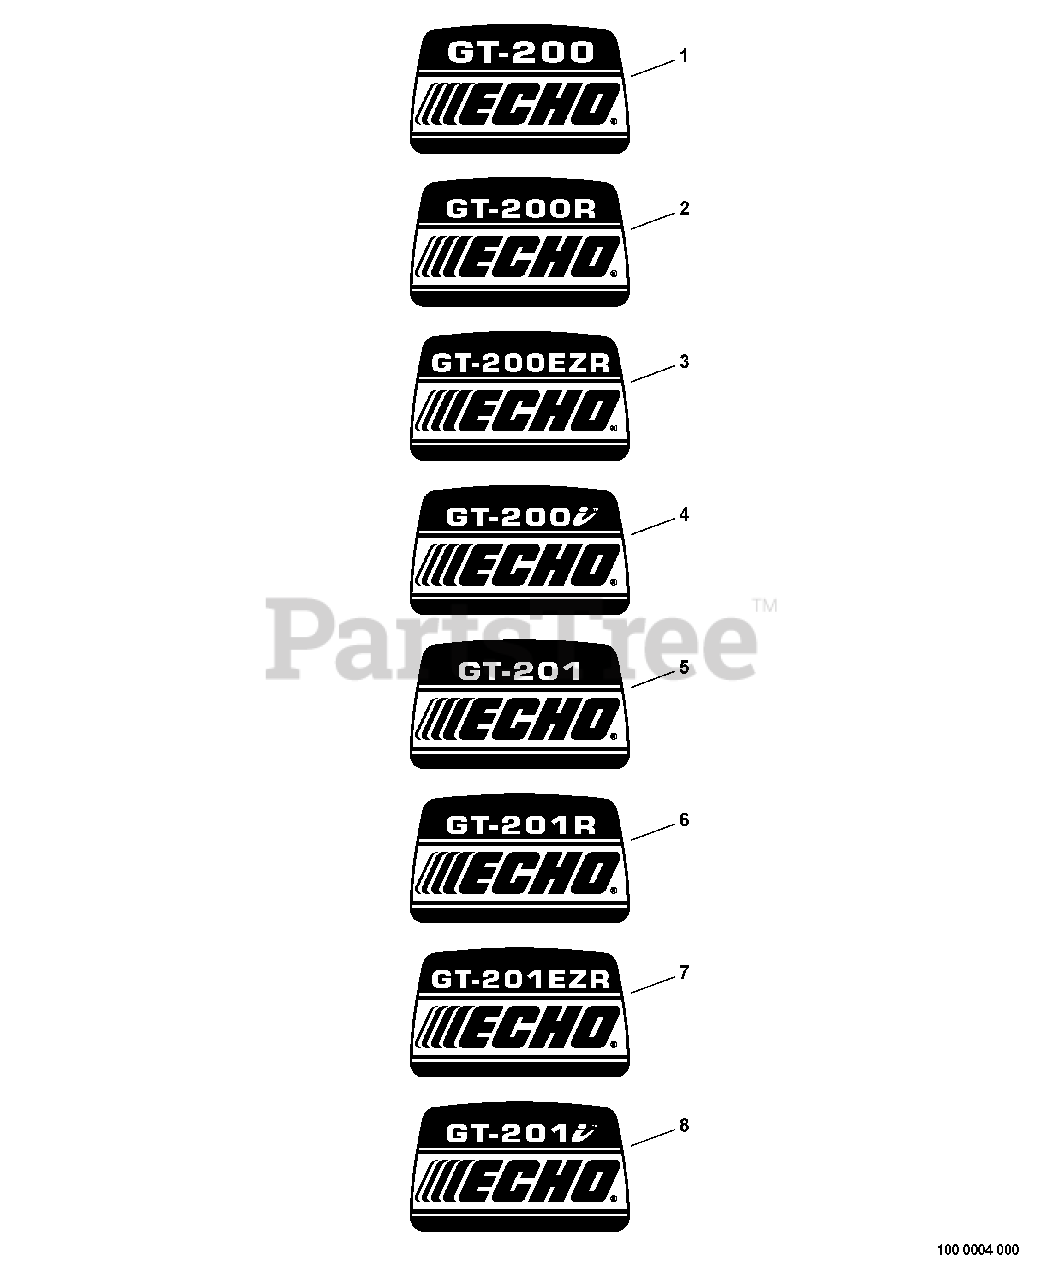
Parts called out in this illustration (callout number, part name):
1	LABEL, MODEL
2	LABEL - MODEL GT-200R
3	LABEL, MODEL
4	LABEL, MODEL
5	LABEL, MODEL
6	LABEL, MODEL
7	LABEL, MODEL
8	LABEL, MODEL
